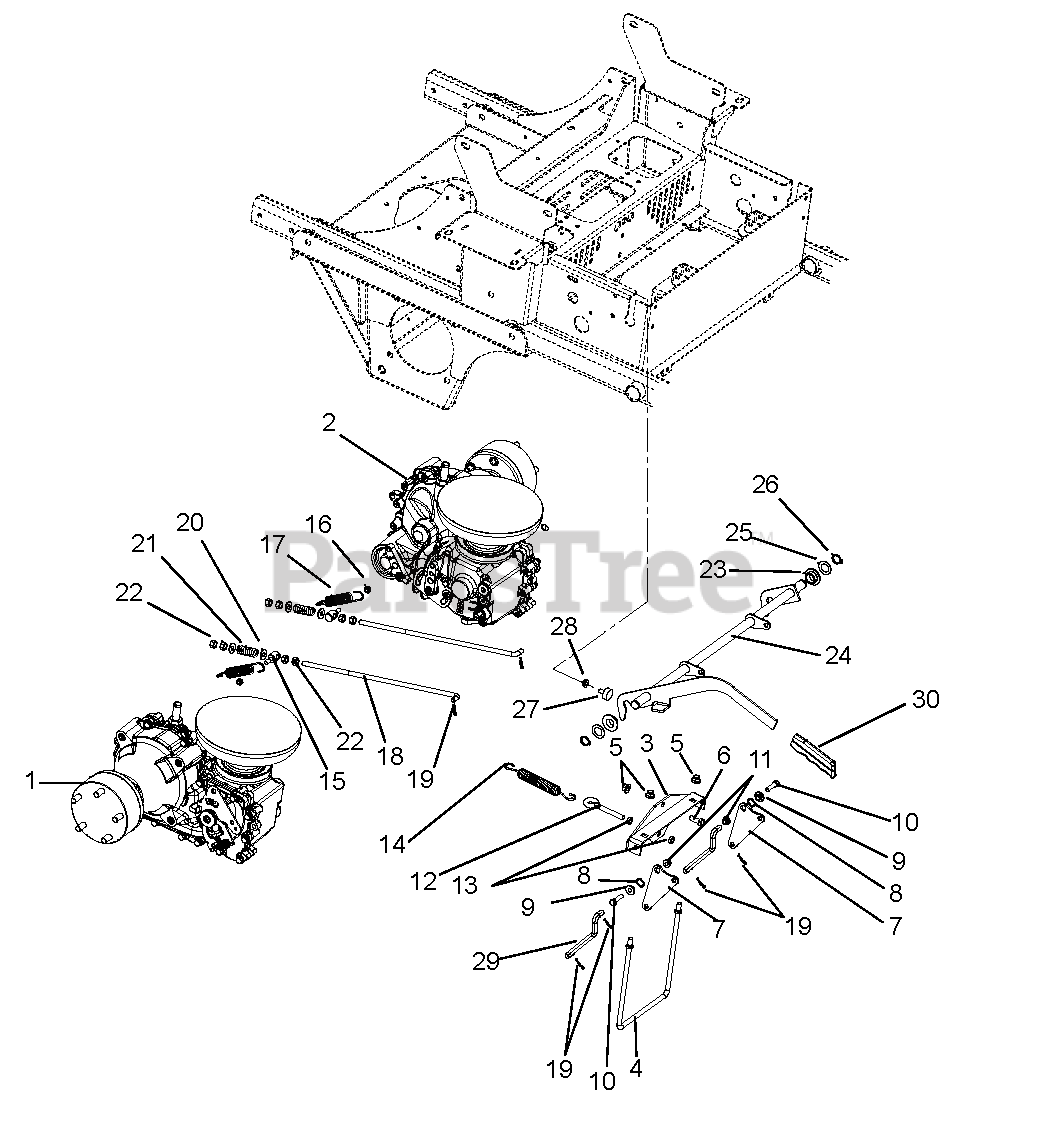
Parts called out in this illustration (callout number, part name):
1	Transmission, Right Hand HG ZT-5400
2	Transmission, Left Hand HG ZT-5400
3	Weldment, Spring Anchor Bracket
4	Rod, Brake Mounting
5	Nut, Locking Nylon Flange .38-16 YWZC
6	Bolt, Hex .38-16 x 1.00 GR5 YWZC
7	Plate, Brake Pivot
8	Wave Washer .531 x .781 x .125FH
9	Bushing, Flange .32 x .500 x .344 x .880
10	Bolt, Hex .31-18 x 1.25 GR5 YWZC
11	Nut, Locking Nylon Flange .31-18 YWZC
12	Bolt, Eye .375-16 x 2.50 YWZC
13	Nut, Hex Jam .375-16 YWZC
14	Spring, Extension
15	Trunnion, .38-16
16	Nut, Locking Center Jam .31-18 YWZC
17	Spring, Tension .105 x .85 x 5.00 WLD 40
18	Rod, Brake Adjustment
19	Pin, Hair
20	Washer, Flat Steel .38 x .875 x .083 YWZC
21	Spring, Compression .142 x .710 x 1.75
22	Nut, Hex .38-16 YWZC
23	Bushing, Flange .762 x 1.48 x .44 NYL
24	Weldment, Brake Interlock
25	Washer, Hardened Thrust .758 x 1.23 x .031
26	Ring, Retaining External .689 x .078
27	Bumper, Rubber
28	Nut, Spin Lock Flange .312-18 YWZC
29	Linkage, Brake Actuating
30	Grip, Parking Brake (Yellow)
